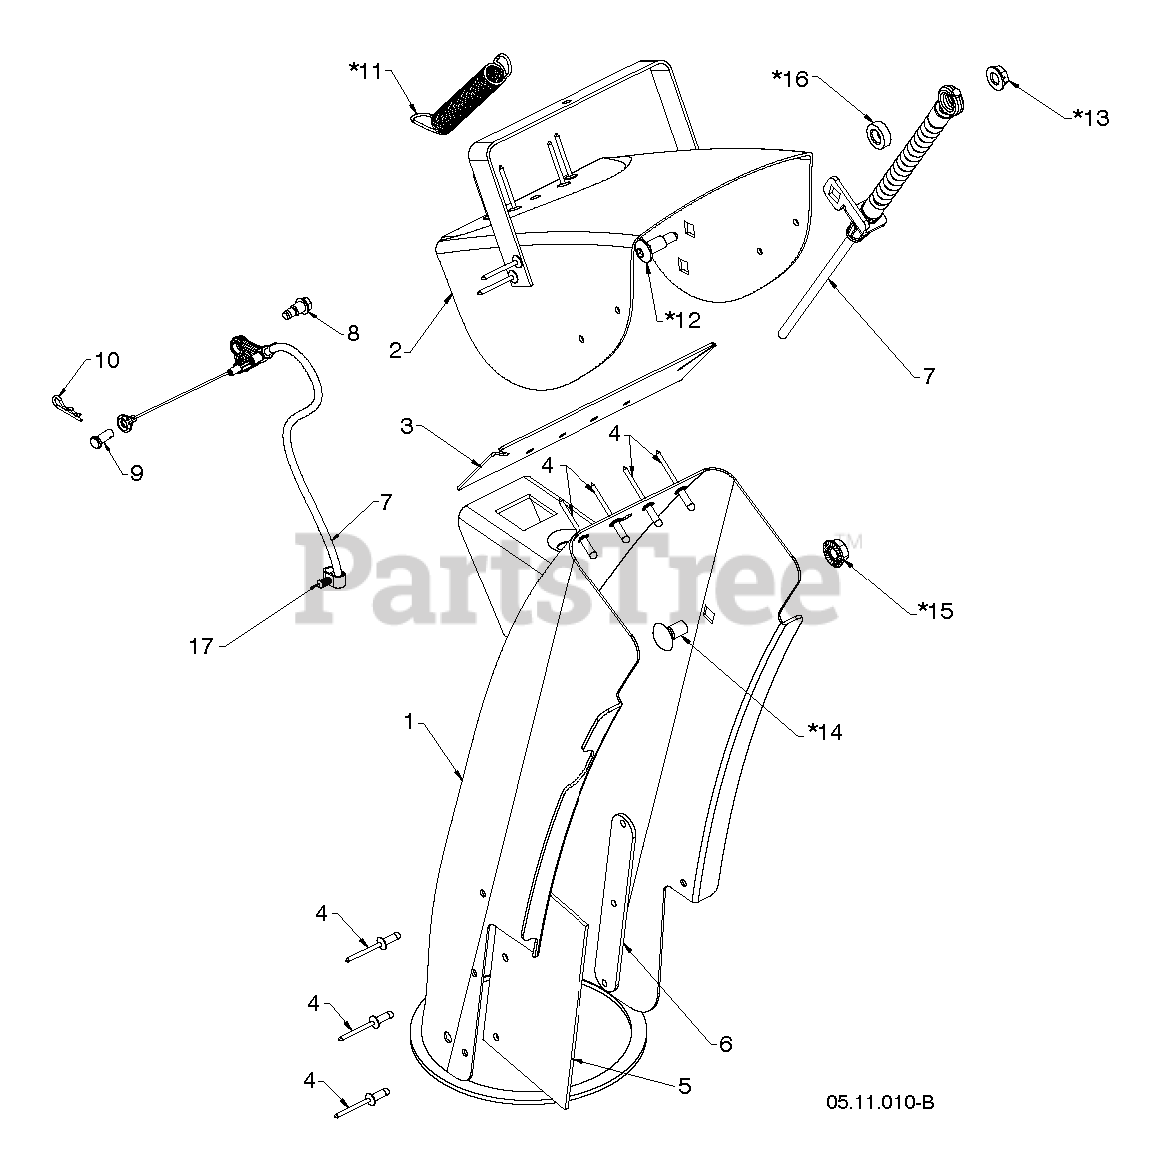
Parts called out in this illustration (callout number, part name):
1	CHUTE.WELDMENT.SNOW.ORANGE
2	ASM.CHUTE/DEFLECTOR.668
3	SEAL.DEFLECTOR
4	RIVET BLIND
5	SHIELD.SNOW.CHUTE
6	RP STRAP.SHEILD.RETAINER
7	CABLE CONTROL.CHUTE.DEFLECTOR.
8	BOLT SHOULDER_1/4-20_TRILOB
9	PIN CLEVIS .25 X ..4375
10	HAIRPIN.SOFT.ZINC.059X1.125
17	CLIP.ROUTING DUAL
